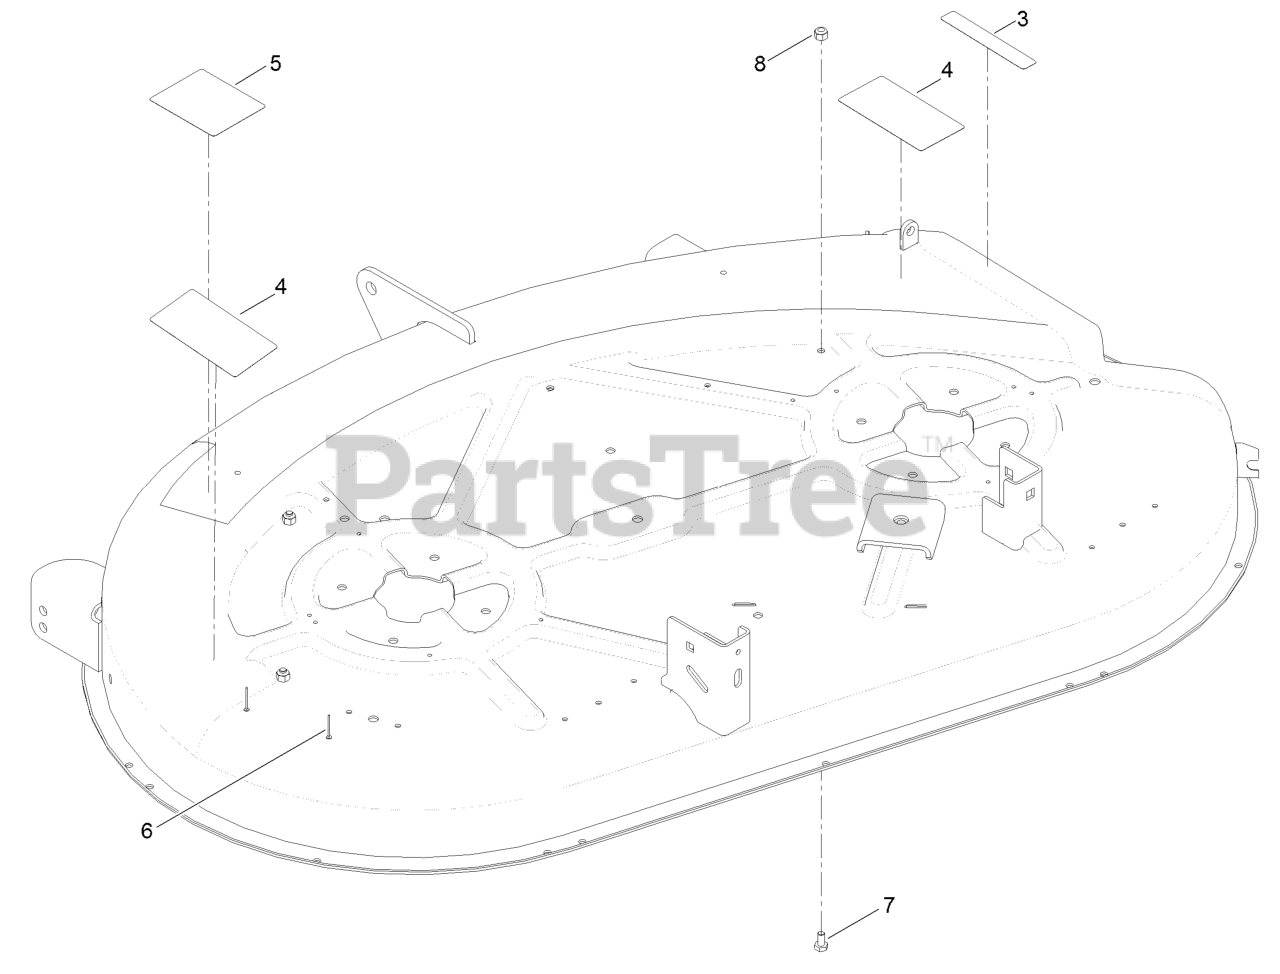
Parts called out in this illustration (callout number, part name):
3	DECAL-DANGER
4	DECAL-DANGER, DECK
5	DECAL-ROUTING, BELT
6	RIVET-BLIND
7	SCREW-HH
8	NUT-LOCK, NI
